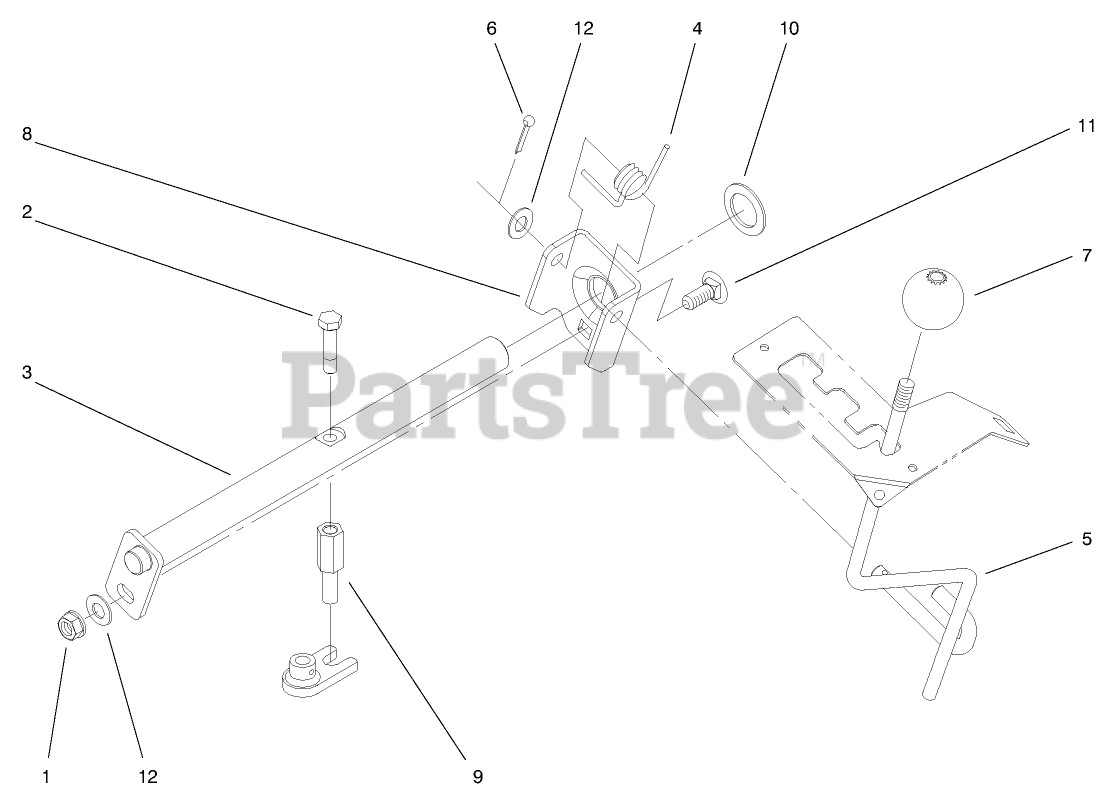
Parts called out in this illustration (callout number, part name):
1	NUT-LOCK, NI
2	SCREW-THREAD LOCKING
3	SHIFT ROD ASM
4	SPRING-TORSION
5	LEVER-SHIFT
6	PIN-COTTER
8	BRACKET-PIVOT
9	ROD-PIVOT, SHIFT
10	SPACER
11	SCREW-CARR
12	WASHER-FLAT
